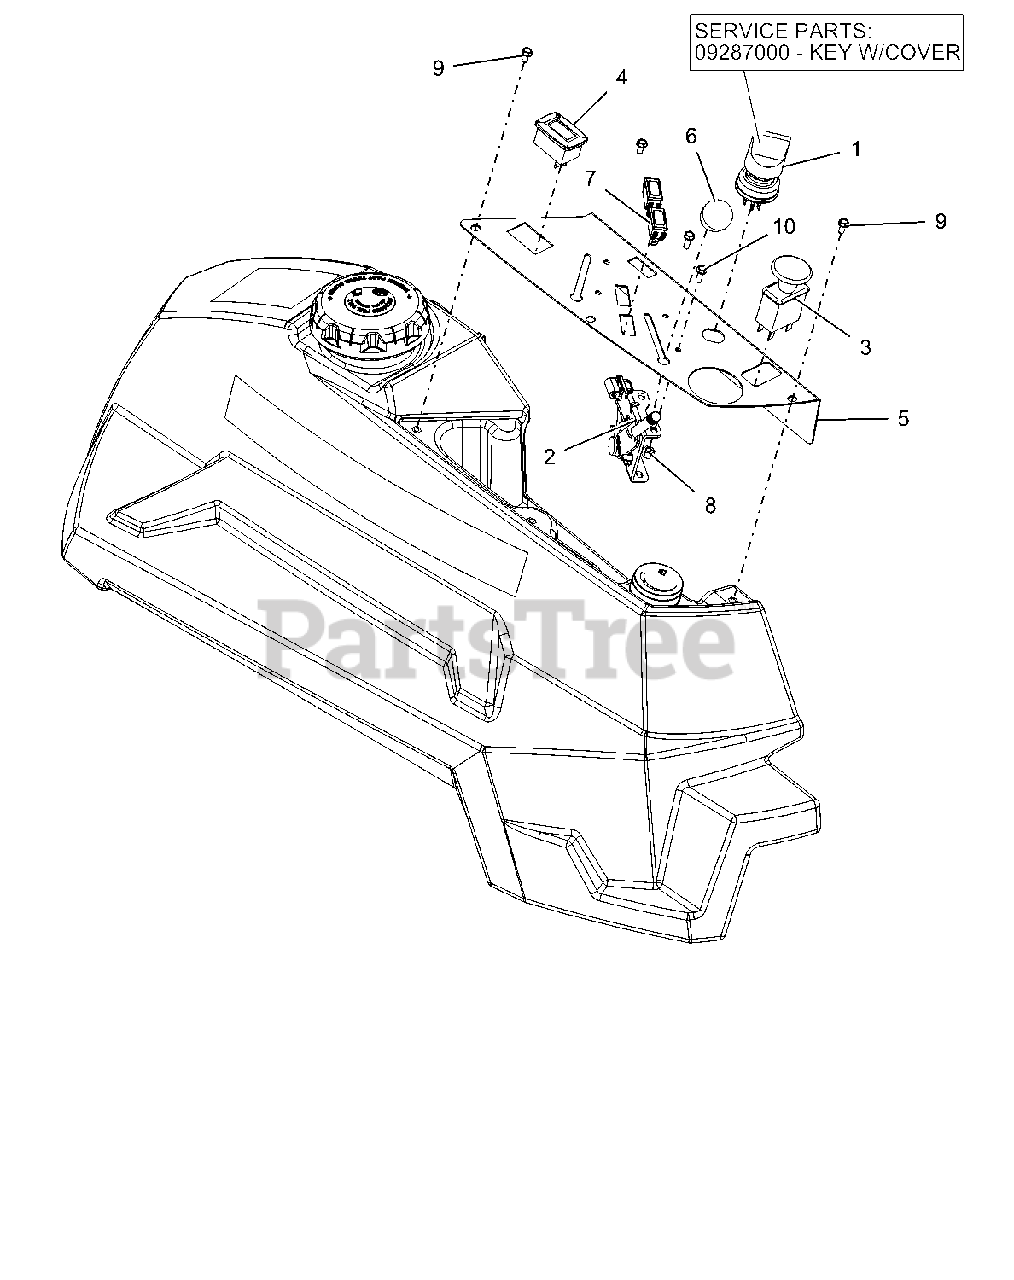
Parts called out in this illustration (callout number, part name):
1	SWITCH, IGNITION
1	KEY W/ COVER
2	CABLE, PRO - CONTROL 35.50"
3	SWITCH, CLUTCH
4	METER, HOUR W/MAINTENANCE
5	PANEL, PT400 CONTROL (RED)
6	KNOB, CONTROL BLACK .38-16X.50
7	LIGHT, INDICATOR
8	NUT-LK-NYL #10-24 YWZC
9	SCR-MCH 10-24X.38 HWHSTAINLESS
10	@SCR-MCH 10-24X.50 HWH YWZC
